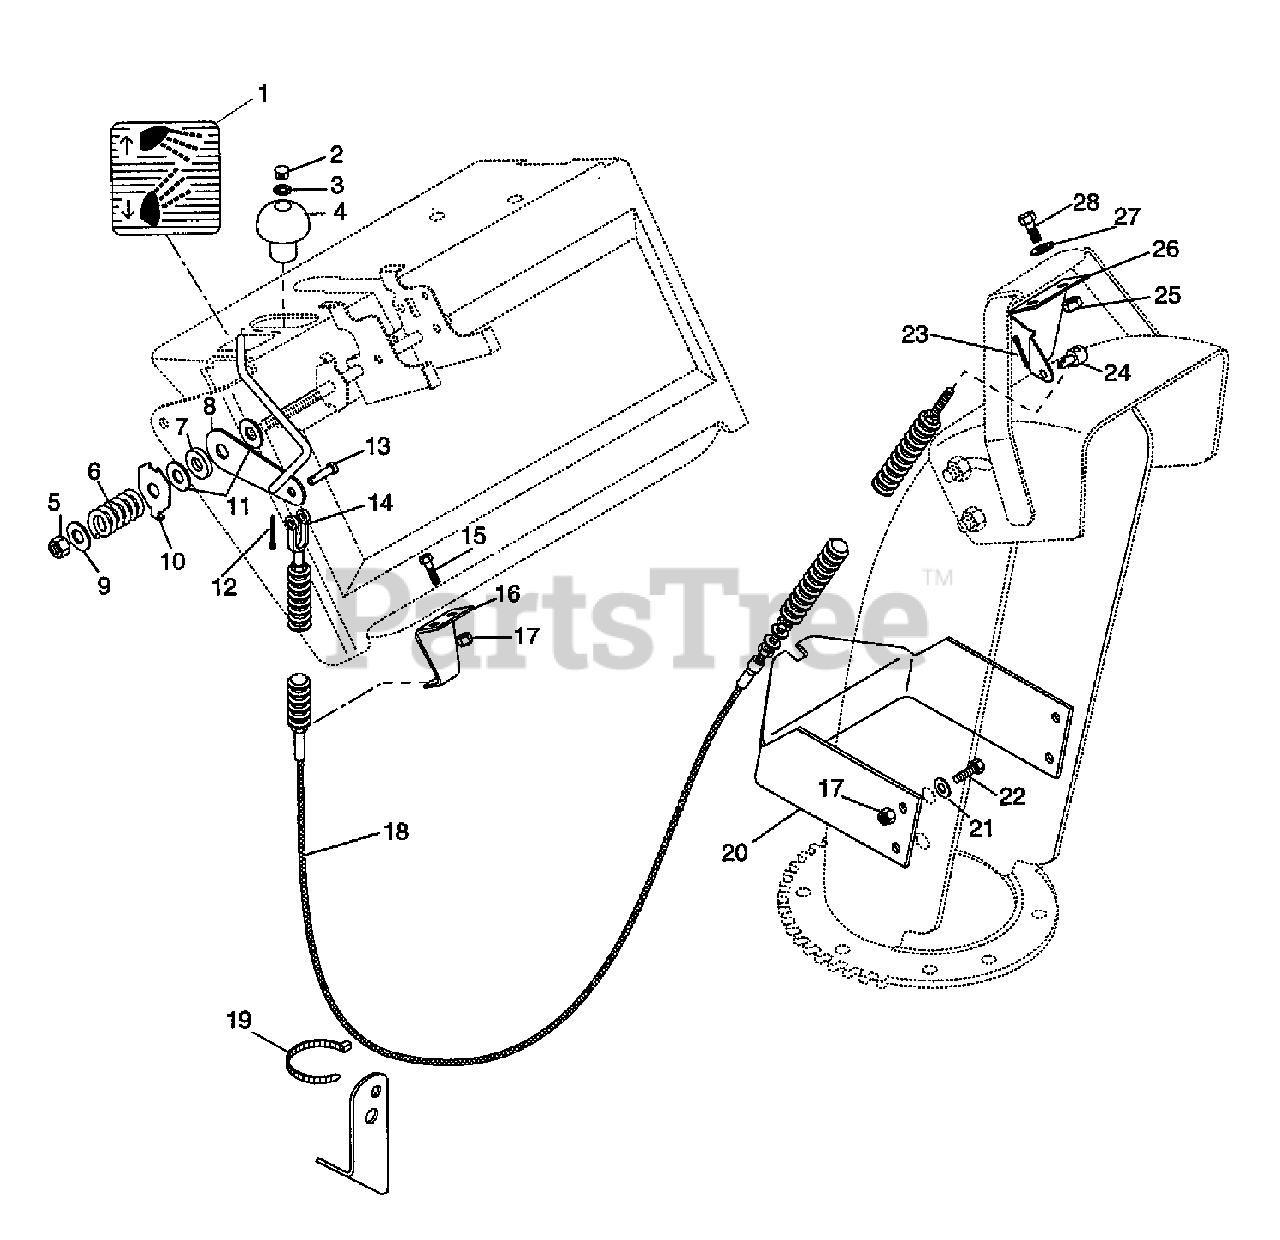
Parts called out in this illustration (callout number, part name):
1	DECAL - DEFLECTOR CONTROL
2	HOLE PLUG
3	RG-RTNG-EXT .375X.010
5	NUT-LK-CTR .375-16 GR A PL
6	SG-COMP .187X.56X1.62
7	SPACER .406X.620X.125
8	LEVER-DEFLECTOR
9	WSHR-FL-STL.406X.812X.065PL
10	PRESSURE FLANGE
11	FRICTION WASHER
12	PIN-COTR .06X.50
13	CLEVIS PIN
15	BLT-HEX .25-20X1.25 PL GR5
16	BRACKET, ROD
17	NUT-LK-CTR .250-20 PL
18	CONTROL CABLE
19	KNOB & LEVER ASS'Y
20	BRKT-CHUTE CABLE
21	WSHR-FL-STL.281X.62X.065 PL
22	BLT-HEX .25-20X.50 PL GR5
23	PIN-COTR .09X.75 PL
25	NUT-LK-NYL.312-18 PL
26	BRKT-CHUTE DEFLECTOR
27	WSHR-FL-STL.344X.688X.065PL
28	BLT-HEX .31-18X.75 PL GR5
